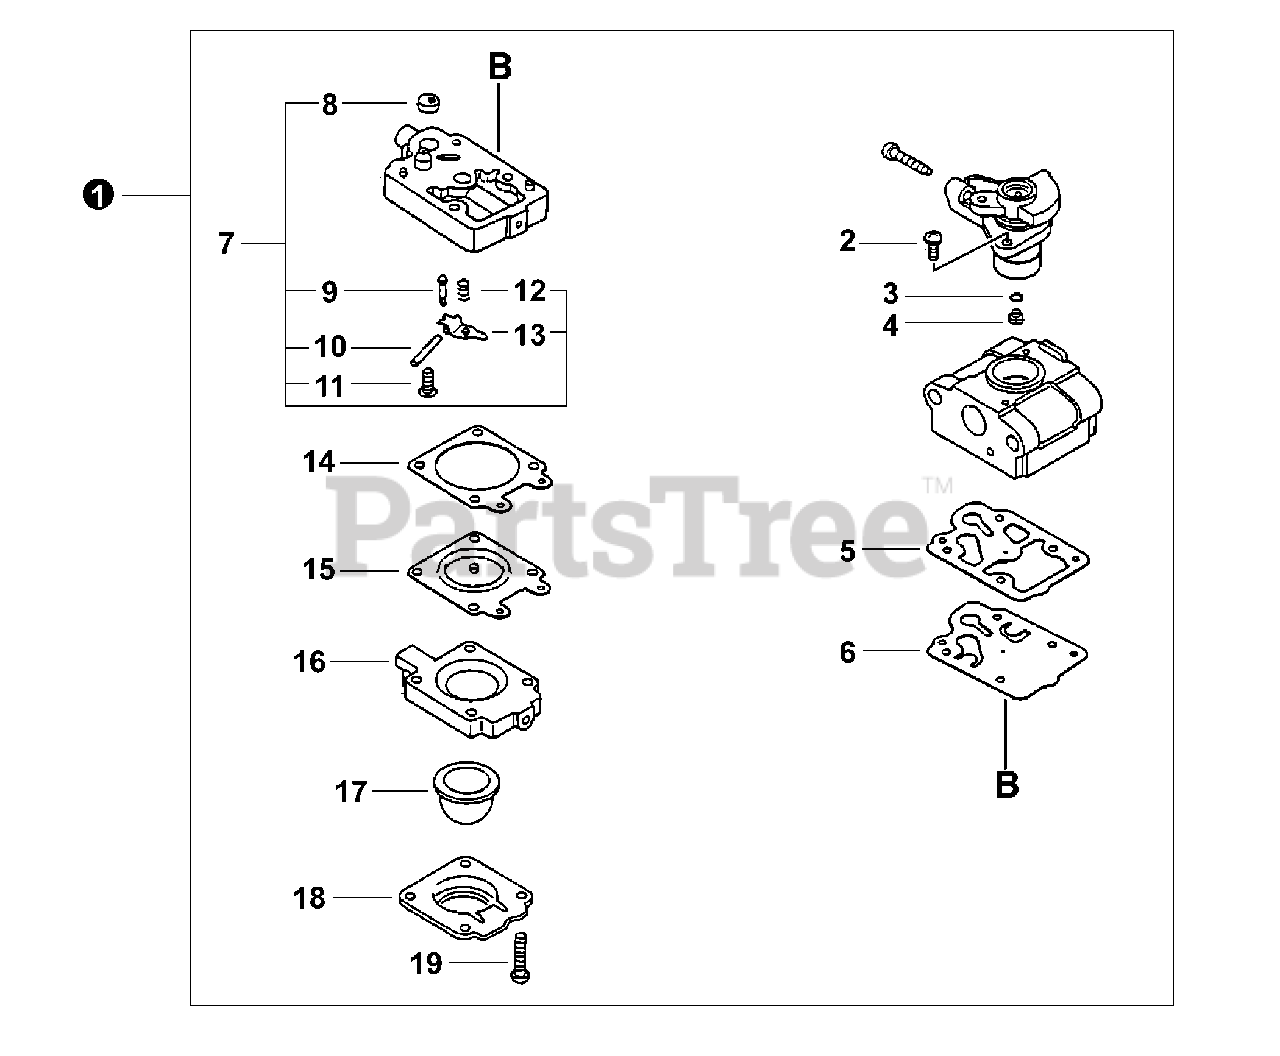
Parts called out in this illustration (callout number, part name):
1	CARBURETOR -- WYL-180A
2	SCREW, VALVE
3	O-RING
5	GASKET, PUMP
6	DIAPHRAGM, PUMP
7	BASE, PURGE
8	STRAINER
9	VALVE, INLET NEEDLE
10	PIN, METERING LEVER
11	SCREW, METERING LEVER PIN
12	SPRING, METERING LEVER
13	LEVER, METERING
14	GASKET, METERING
15	DIAPHRAGM, METERING
16	BASE, PURGE
17	BULB, PURGE
18	RETAINER, PURGE BULB
19	SCREW, PUMP COVER
